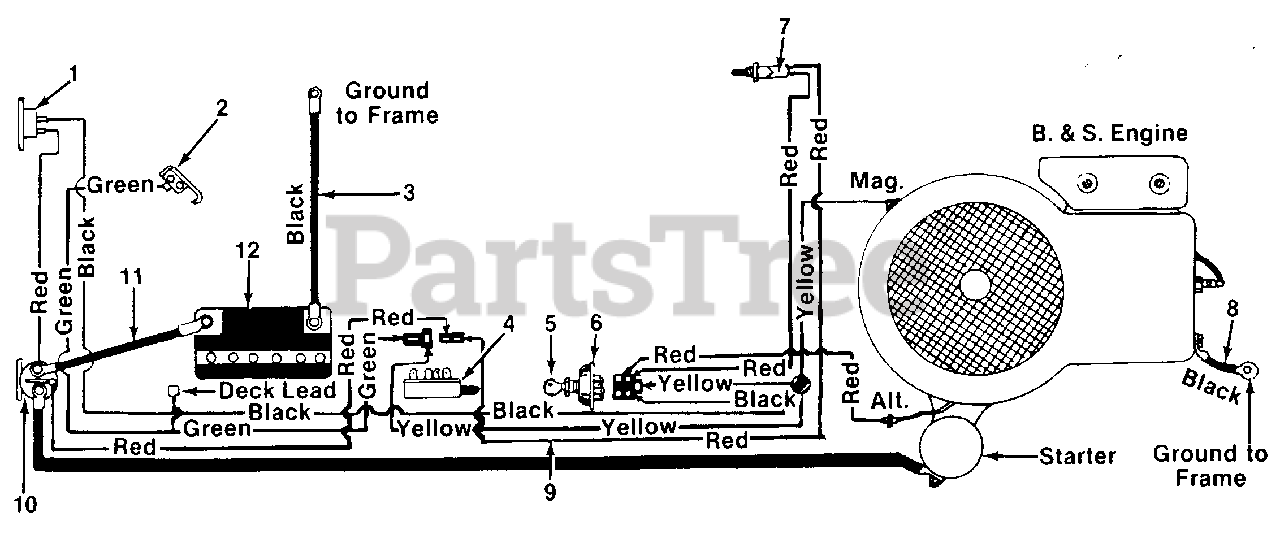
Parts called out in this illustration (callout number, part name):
1	Circuit Breaker
2	Spring Switch
3	Ground Wire 9.0" Lg.
4	Safety Switch
5	Ignition Key
6	Ignition Switch
7	Safety Switch
8	Ground Wire 7.25" Lg.
9	Wire Harness
10	Solenoid
11	Electric Wire w/ Boot
12	12V-Battery
